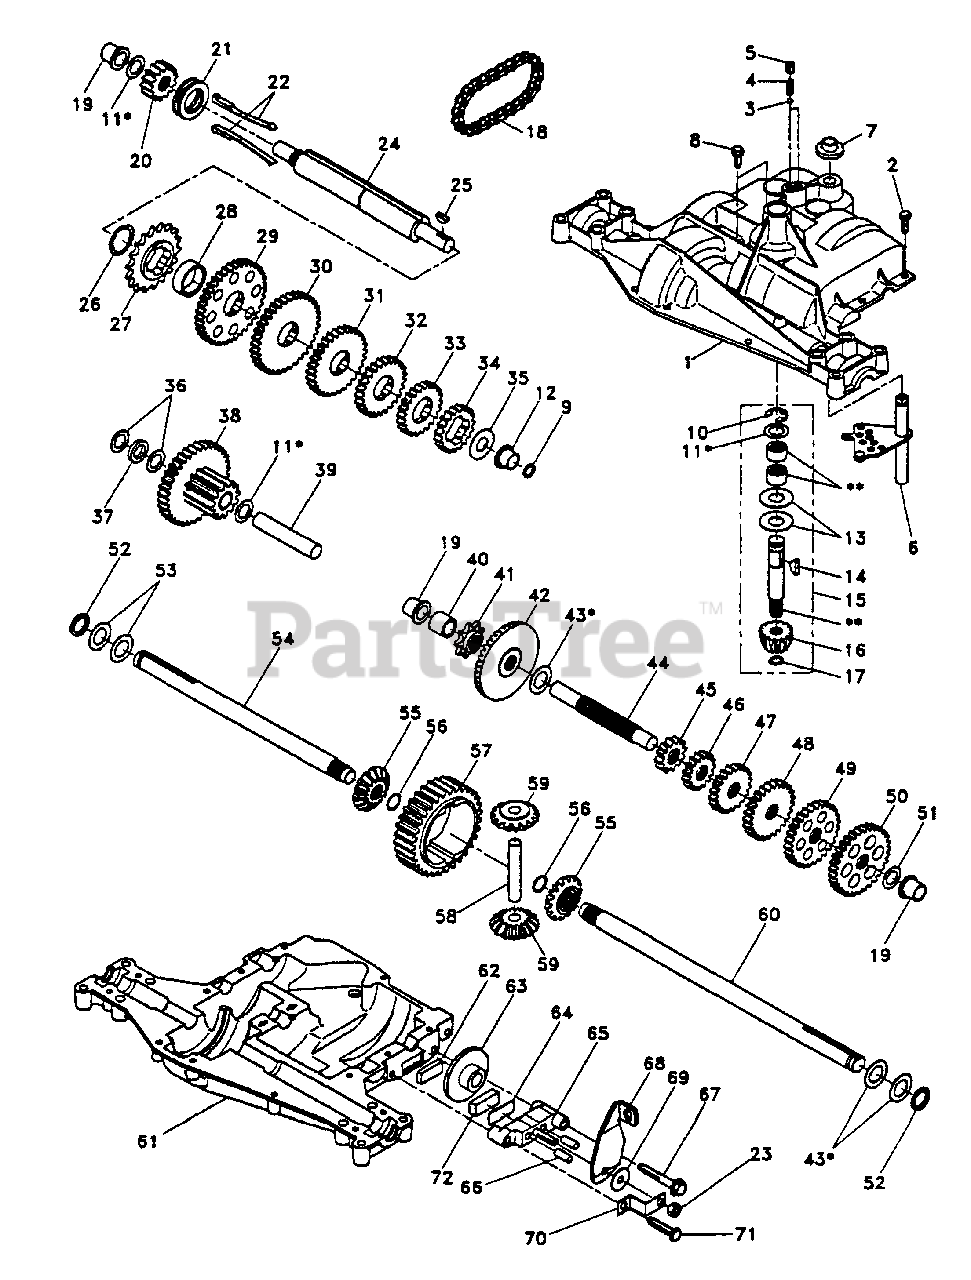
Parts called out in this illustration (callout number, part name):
1	Housing, Upper
2	Screw, Self-Tapping, Large 1/4-20 x .734
3	Ball, Detent
4	Spring, Detent
5	Screw, Set
6	Kit, Shifter Assembly
7	Boot, Shifter
8	Screw, Self-Tapping, with Sealer
9	Square Ring
10	Ring, Retaining
11	Assembly, Kit, Shim .625 Shaft
12	Bearing, Flange
13	Washer, Plain .632 x 1.38 x .046
14	Key, Woodruff, #9
15	Assembly, Kit, Input Shaft
16	Pinion, Bevel, 14 Teeth
17	Ring, Retaining
18	Chain, 24 Pitches
19	Bearing, Flange
20	Gear, Spur, 14 Teeth
21	Collar, Clutch
22	Assembly, Kit, Clutch Keys
23	Locknut 5/16-24
24	Shaft, Intermediate
25	Key, Woodruff, #61
26	Ring, Retaining
27	Sprocket, 18 Teeth
29	Gear, Spur, 37 Teeth
30	Gear, Spur, 35 Teeth
31	Gear, Spur, 30 Teeth
32	Gear, Spur, 25 Teeth
33	Gear, Spur, 22 Teeth
34	Gear, Spur, 19 Teeth
35	Washer, Plain .640 x 1.37 x .061
36	Washer, Plain .632 x 1.00 x .026
37	Spacer .630 x 1.00 x .169
38	Assembly, Gear, Combination of 12 Teeth and 35 Teeth
39	Shaft, Idler
40	Spacer .635 x .875 x .755
41	Sprocket, 9 Teeth
42	Gear, Bevel, 42 Teeth
43	Assembly, Kit, Shim .750 Shaft
44	Shaft, Drive
45	Gear, Spur, 12 Teeth
46	Gear, Spur, 15 Teeth
47	Gear, Spur, 20 Teeth
48	Gear, Spur, 25 Teeth
49	Gear, Spur, 28 Teeth
50	Gear, Spur, 31 Teeth
51	Washer, Plain .632 x 1.00 x .060
52	Washer, Neoprene
53	Washer, Plain .758 x 1.25 x .031
54	Axle, L.H.
55	Gear, Miter, 15 Teeth
56	Ring, Retaining
57	Gear, Spur, 32 Teeth
58	Shaft, Cross
59	Gear, Miter, 15 Teeth
60	Axle, R.H.
61	Housing, Lower
62	Puck, Friction
63	Disc, Brake
65	Jaw, Brake
66	Pin, Dowel
67	Screw, Self-Tapping, Large 5/16-18 x 2.25
68	Lever, Actuating
69	Washer, Plain .321 x 1.00 x .055
70	Bracket, Anti-Rotation
71	Screw, Self-Tapping, Large 5/16-18 x 1.44
72	Puck, Friction
73	Grease
